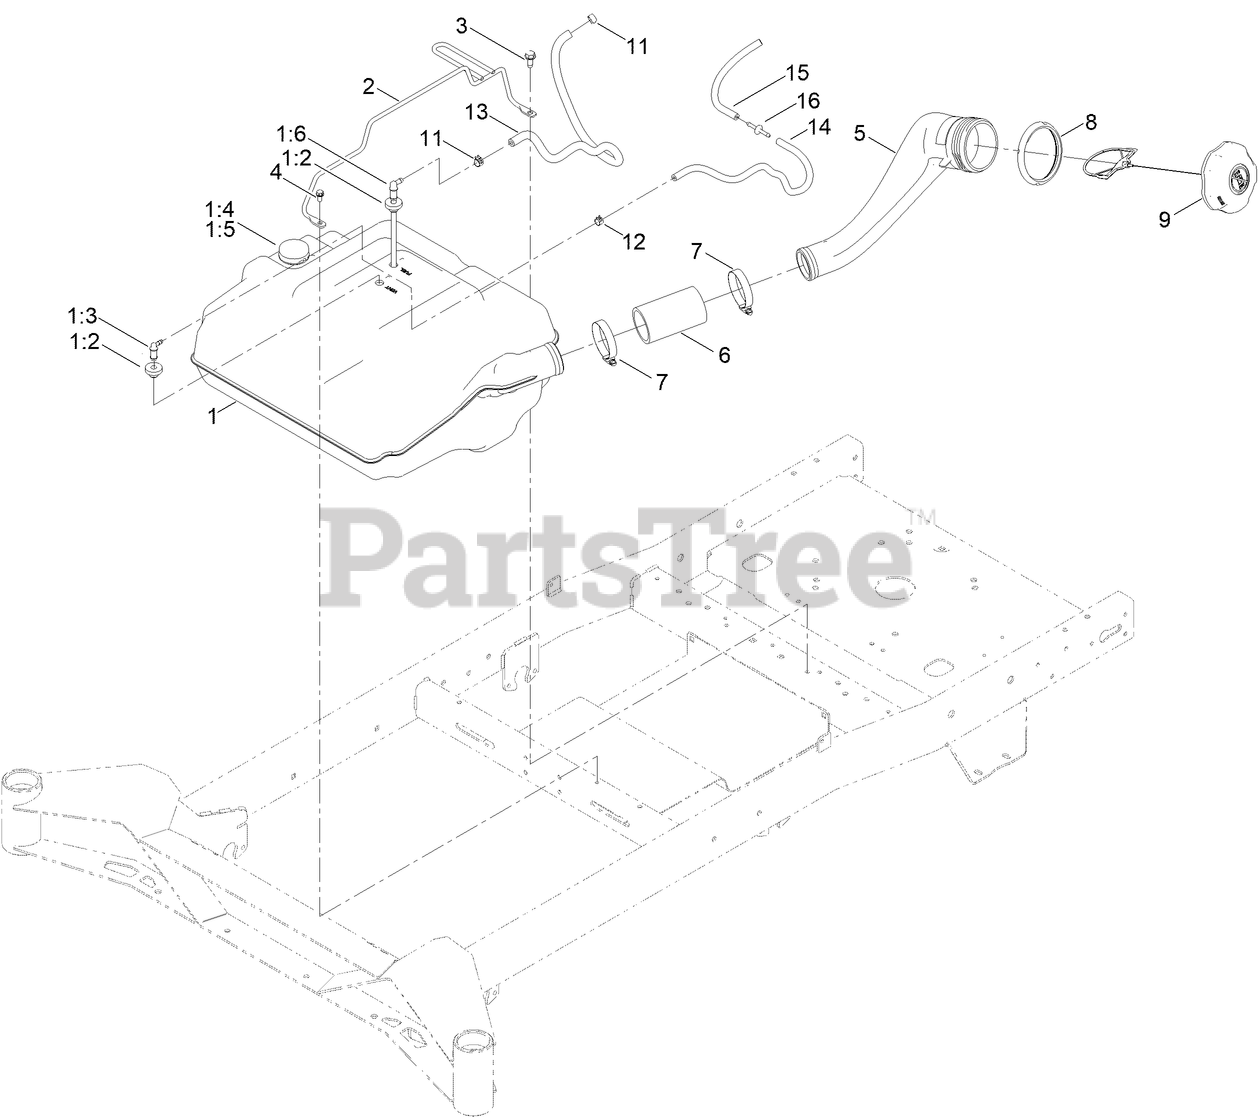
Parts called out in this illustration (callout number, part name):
1	TANK ASM-FUEL
1:2	BUSHING
1:3	FITTING-ELBOW 90
1:4	GROMMET-FUEL
1:5	REMOTE GAUGE ASM
1:6	FITTING - PICKUP, FUEL
2	HOLD DOWN ASM
3	SCREW-HWHTF
4	SCREW-HWH
5	NECK-FILLER, FUEL
6	HOSE-FILLER, FUEL
7	CLAMP-HOSE
8	RING-RETAINING
9	CAP FUEL, RATCHETING
11	CLAMP-HOSE
12	CLAMP-HOSE
13	HOSE-FUEL
14	HOSE-FUEL
15	HOSE-FUEL
16	ADAPTER ORIFICE
